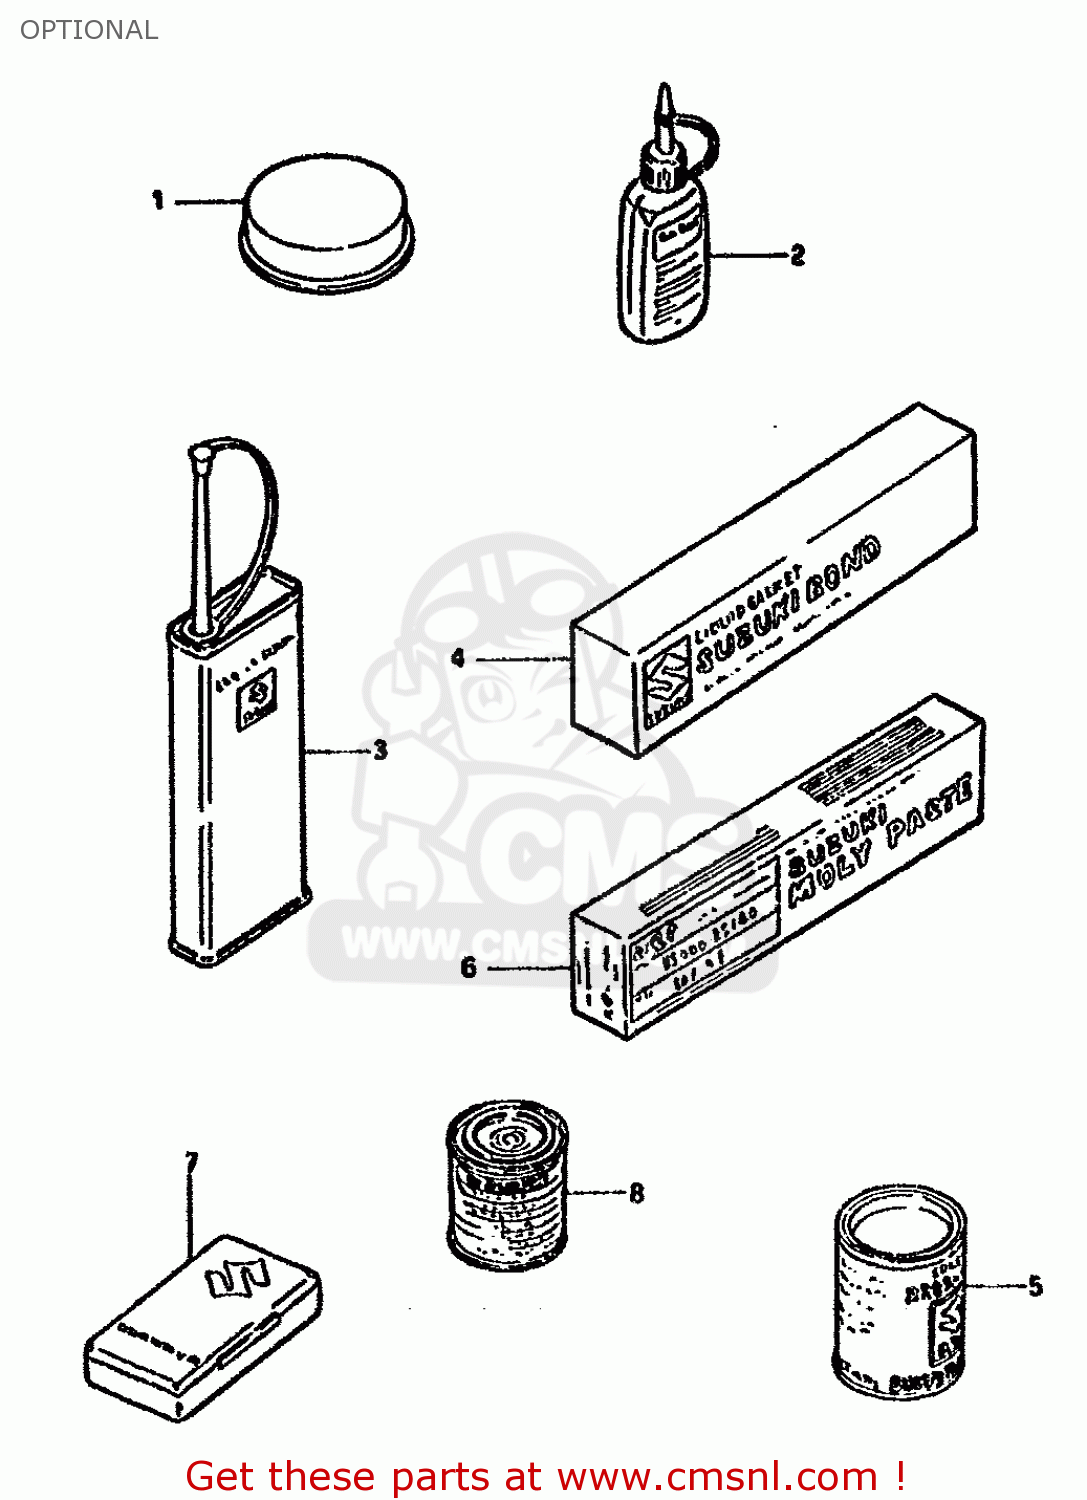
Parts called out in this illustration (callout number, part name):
1	GREASE,PBC FOR BRK PAD 20G
2	THREAD LOCK NO.1342
3	THREAD LOCK NO.1401 CLEAR 200G
4	LIQUID GSKT NO.1215 250G
5	GREASE(C)EP2 LITHIUM 150G
6	SUZUKI MOLY PASTE
7	TUBE REPARING TOOL
8	PAINT,BLACK
